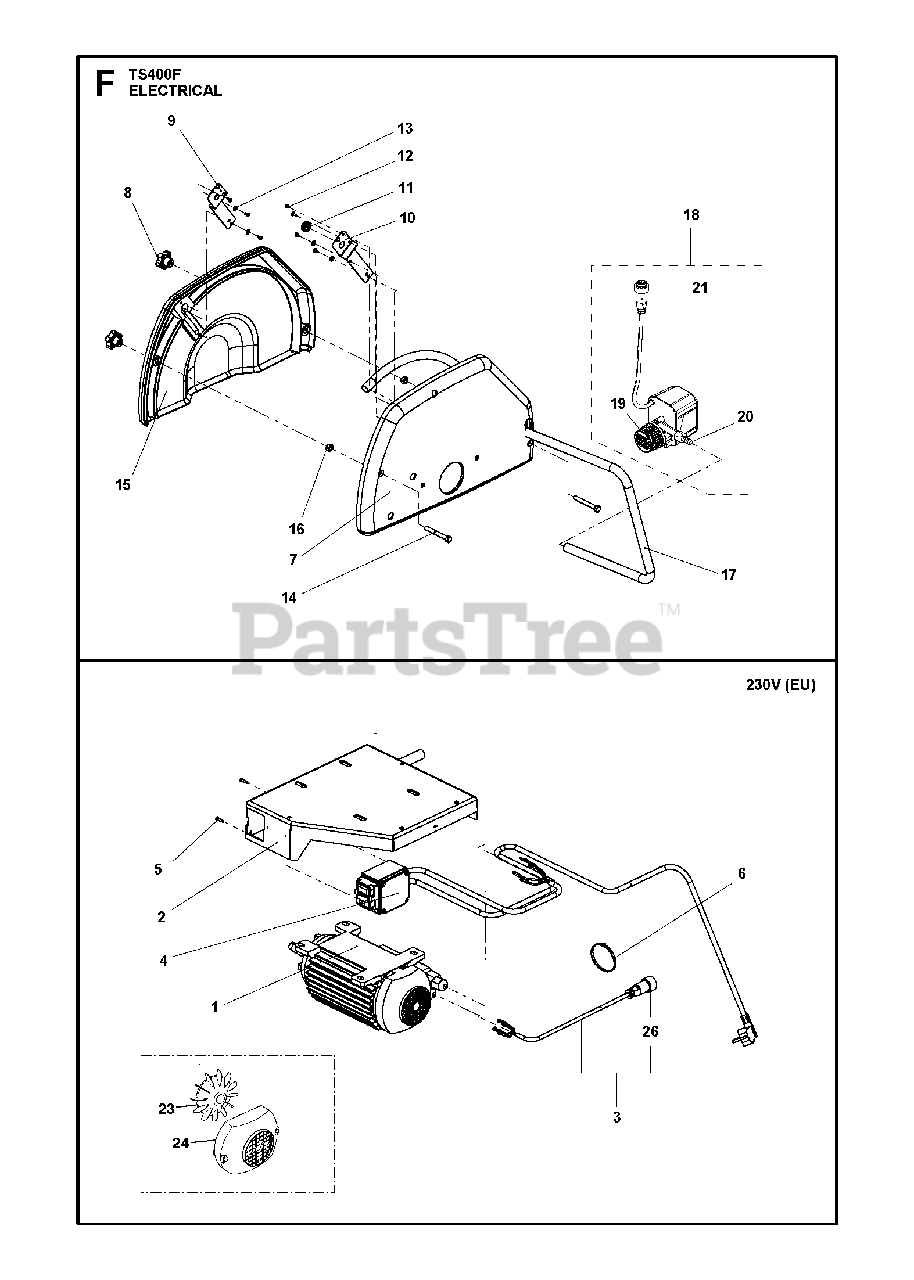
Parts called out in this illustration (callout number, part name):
9	WATER DISPENCER 1TS400F
11	PASSE FIL DA 110X140X30/
16	HEXAGON NUT
20	ADAPTATOR FOR FILTERFor 115V pump
22	BYPASS TEE FOR PUMP 25W*
